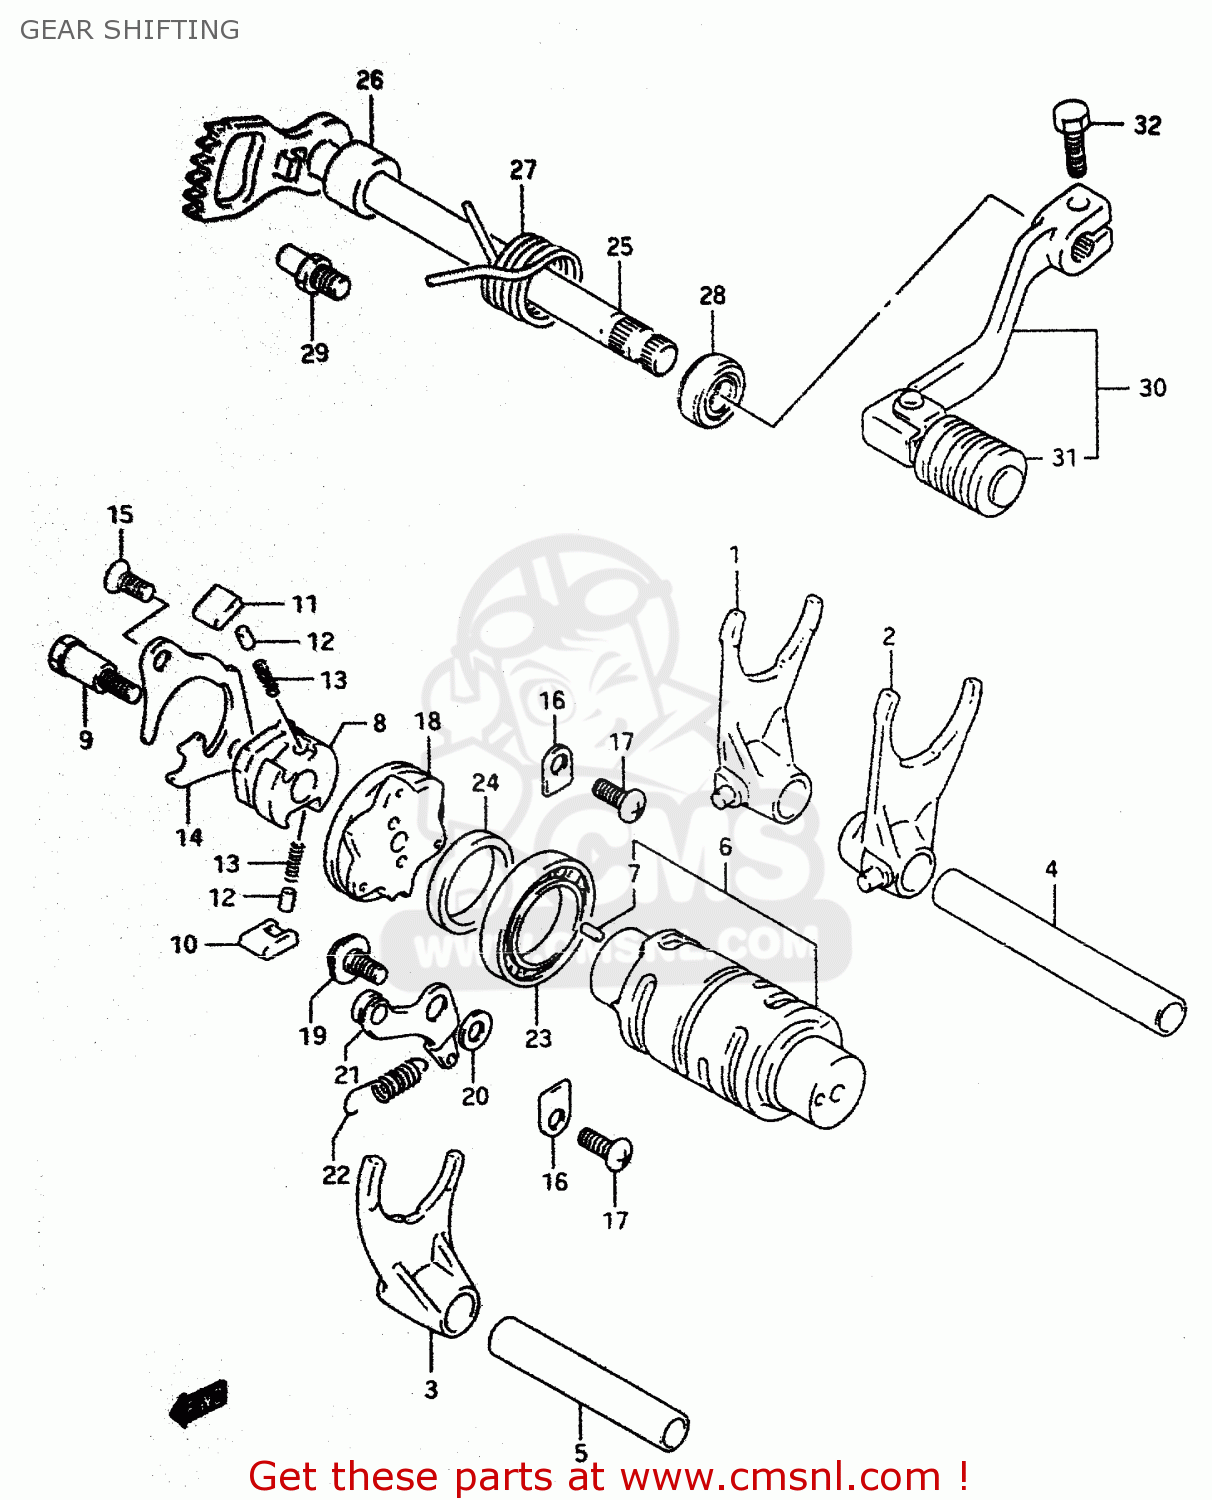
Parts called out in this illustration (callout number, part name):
1	FORK,GEAR SHIFT NO.1
2	FORK,GEAR SHIFT NO.2
3	FORK,GEAR SHIFT NO.3
4	SHAFT,GEAR SHIFT FORK
5	SHAFT,GEAR SHIFT FORK(L:70)
6	CAM,GEAR SHIFT
7	PIN
8	GEAR,GEARSHIFT CAM DRIVE
9	PIN,SHIFT CAM DRIVEN GEAR
10	PAWL,GEAR SHIFT NO.1
11	PAWL,GEAR SHIFT NO.2
12	PIN(5X8)
13	SPRING
14	LIFTER,GEAR SHIFT PAWL
15	SCREW
16	RETAINER
17	SCREW
18	PLATE,GEAR SHIFT CAM
19	BOLT(6X14.3)
20	WASHER
21	STOPPER,GEAR SHIFT CAM
22	SPRING
23	BEARING
24	WASHER(25X32X5.3)
25	SHAFT,GEAR SHIFT
26	SPACER(12X20X15.3)
27	SPRING
28	OIL SEAL
29	STOPPER,GEAR SHIFT ARM
30	LEVER ASSY,GEAR SHIFT
31	RUBBER,GEAR SHIFT PEDAL
32	BOLT
